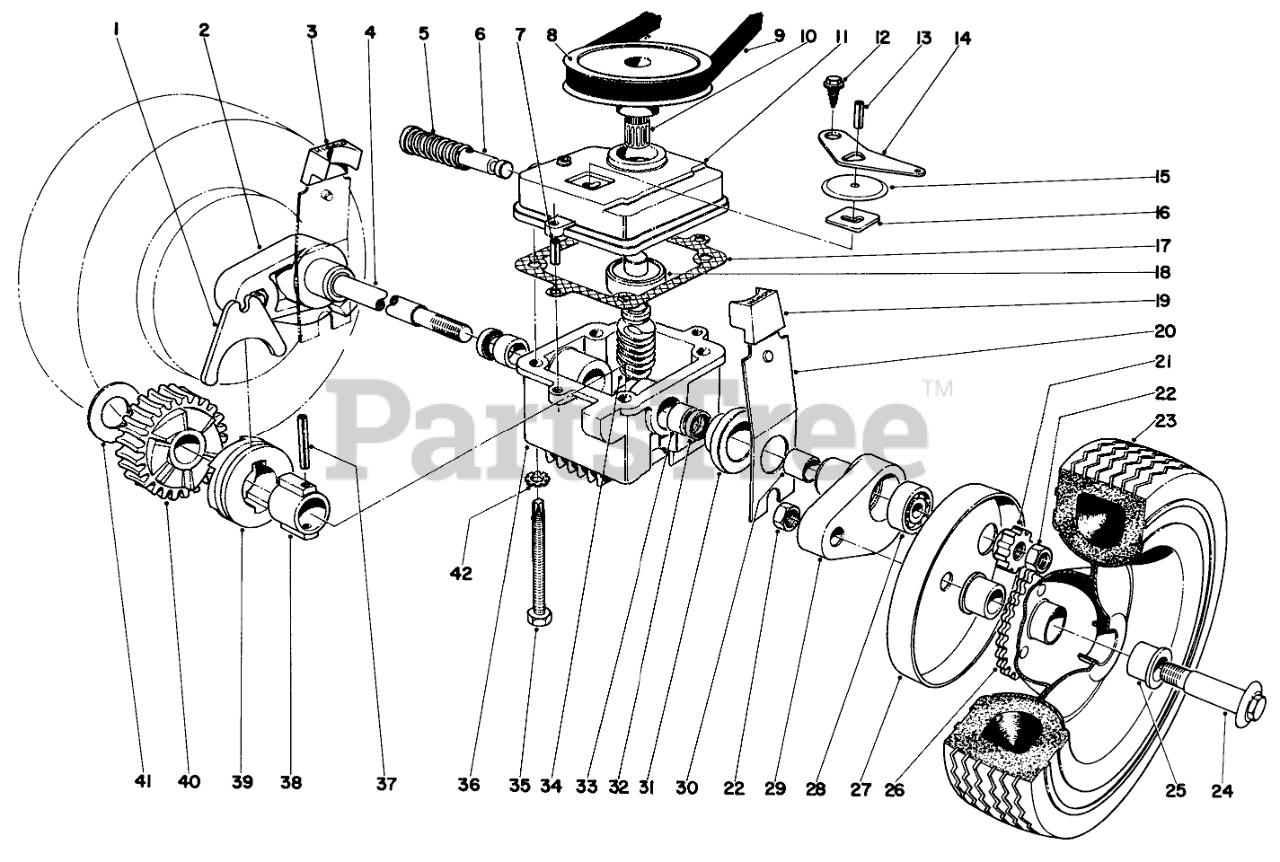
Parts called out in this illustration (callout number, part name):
1	SHIFTER FORK
2	Pivot Arm (Incl. Ref. #30)
4	DRIVE SHAFT
5	SPRING
6	Shift Rod
7	3/16 X 1/2 ROLL PIN
8	PULLEY
9	V BELT
10	TOLERANCE RING
11	GEAR CASE COVER
12	Screw
13	PIN-ROLL
14	SHIFTER ARM
15	TRANS DUST COVER
16	LATCH PLATE
17	GASKET
18	Bearing
19	ARM KNOB
20	Spring Arm
21	PINION GEAR
22	Nut
23	8 TIRE
24	Wheel Bolt
25	FLANGE BUSHING
26	Wheel Assembly
27	WHEEL COVER
28	.375 RPP BALL BEARING
29	Pivot Arm (Incl. Ref. #30)
30	BUSHING
31	End Cap
32	Seal
33	Bushing
34	Worm Shaft
35	Sems Screw
36	Gear Case
37	PIN-SPRING
38	SLEEVE
39	Clutch
40	Worm Gear
41	THRUST WASHER
42	WASHER-LOCK/EXT
